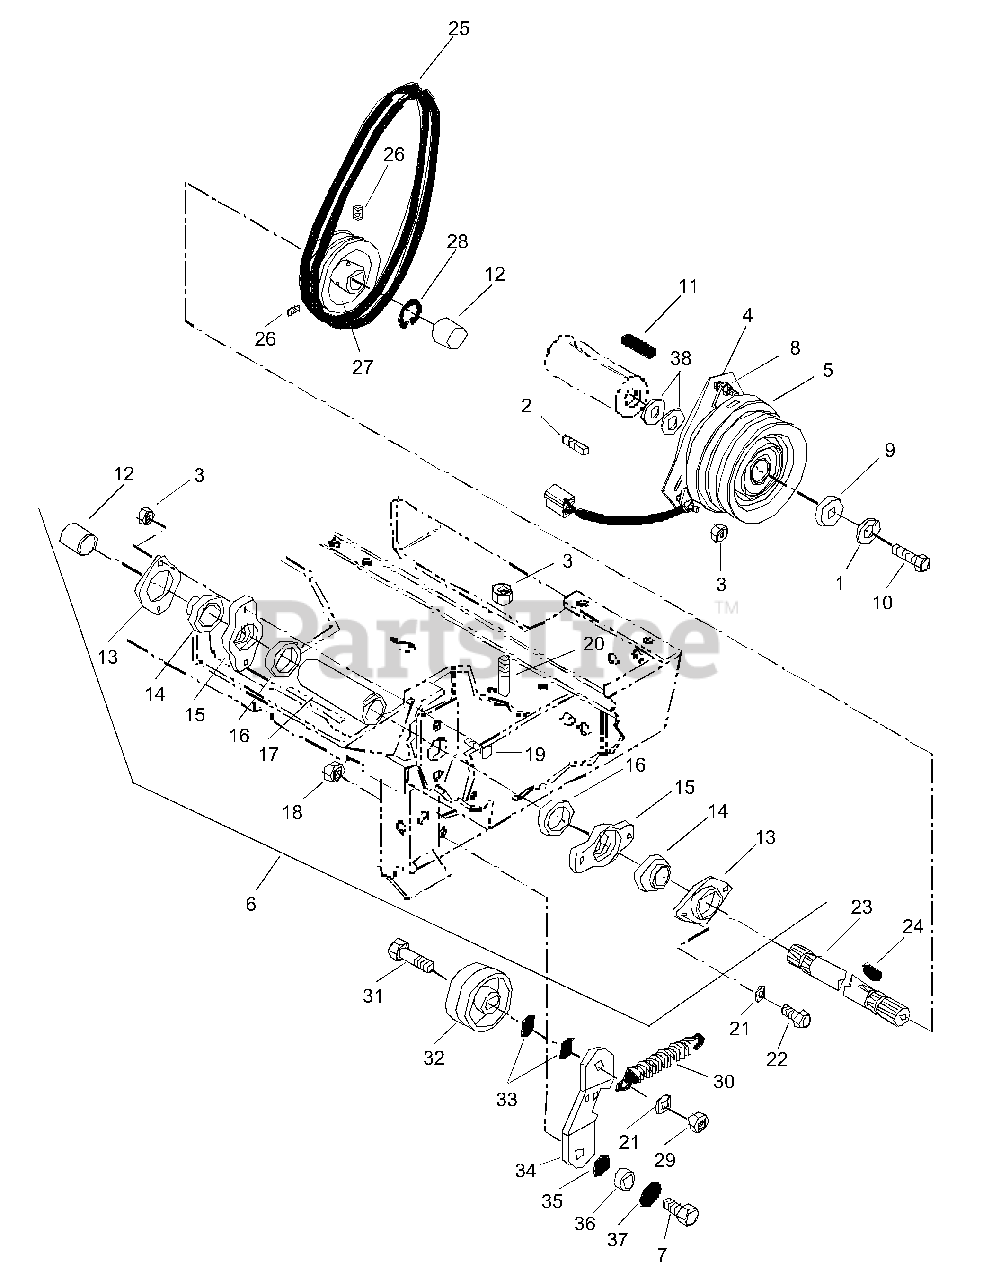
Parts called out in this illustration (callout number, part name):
1	Washer-Locking .438 x .133
2	Stud-Clutch
3	Nut-Locking-Center .38-16
4	Spring-Compression
5	Clutch-Electric
6	Front PTO Kit
7	Bolt-Hex .50-13 x 1.25 Grade 5
8	Nut-Locking
9	Washer-Flat-Steel .515 x 1.625 x .250
10	Bolt-Hex .44-20 x 1.50
11	Key-Square .25 x .625 x .25
12	Shaft Cover
13	Flange
14	Bearing w/Collar 1.0 x 2.047 x .844
15	Bearing Flange
16	Bushing-Sleeve 1.500 x 1.750 x .560
17	PTO Tube
18	Nut-Locking-Center .50-13
19	Bolt-Round Head Square Neck .38-16 x 1.50
20	Lock Stud
21	Washer-Lock .38 x .094
22	Bolt-Hex .38-16 x 1.50 Grade 5
23	Front PTO Shaft
24	Key-Feather .25 x 1.25 x .25
25	Belt-Set
26	Screw-Set .32-18 x .38
28	Ring-Retaining-External 1.00 x .042
29	Nut-Hex .38-16
30	Spring Assembly
31	Bolt-Hex .38-16 x 2.00 Grade 5
32	Idler-Flat 3.25 x .38
33	Washer-Flat-Steel .390 x .75 x .125
34	Idler Arm
35	Shim Spacer
36	Spacer .512 x .747 x .208
37	Washer-Flat-Steel .518 x 2.000 x .105
38	Washer-Bushing 10 Gauge
